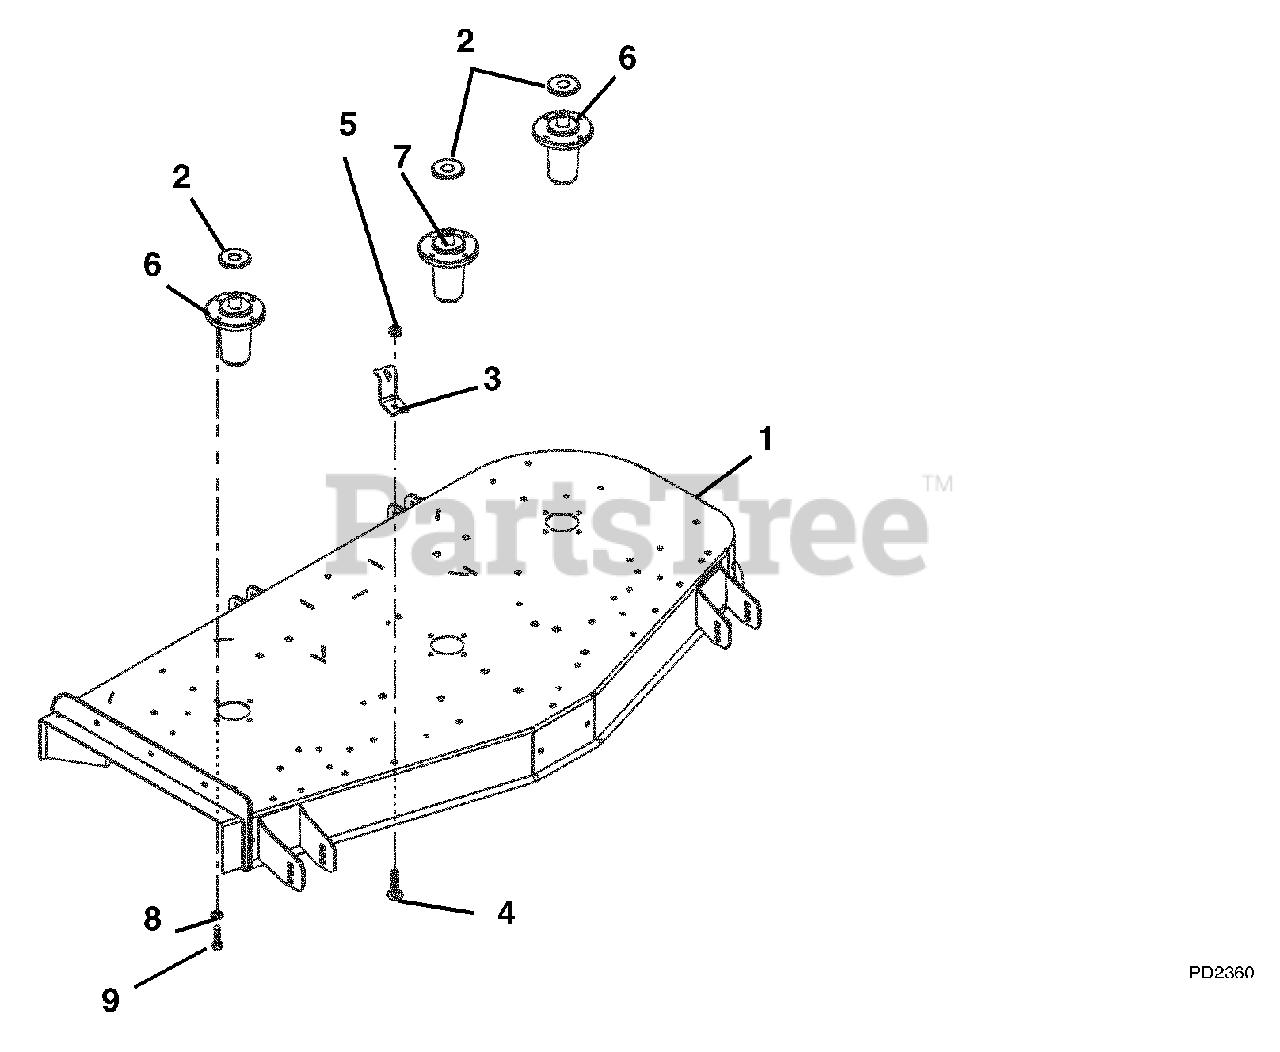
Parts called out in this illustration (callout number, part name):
1	Weldment, 60" Deck (Side Discharge)
2	Slinger-Dust
3	Anchor, Spring
4	Bolt-Round Head Square Neck .38-16 x 1.25 Grade 5
5	Nut-Locking-Nylon .38-16
6	Assembly, Spindle L-Hub
7	Spindle Assembly (Center)
8	Washer-Locking .38 x .094
9	Bolt-Hex .38-16 x 1.00 Grade 5
